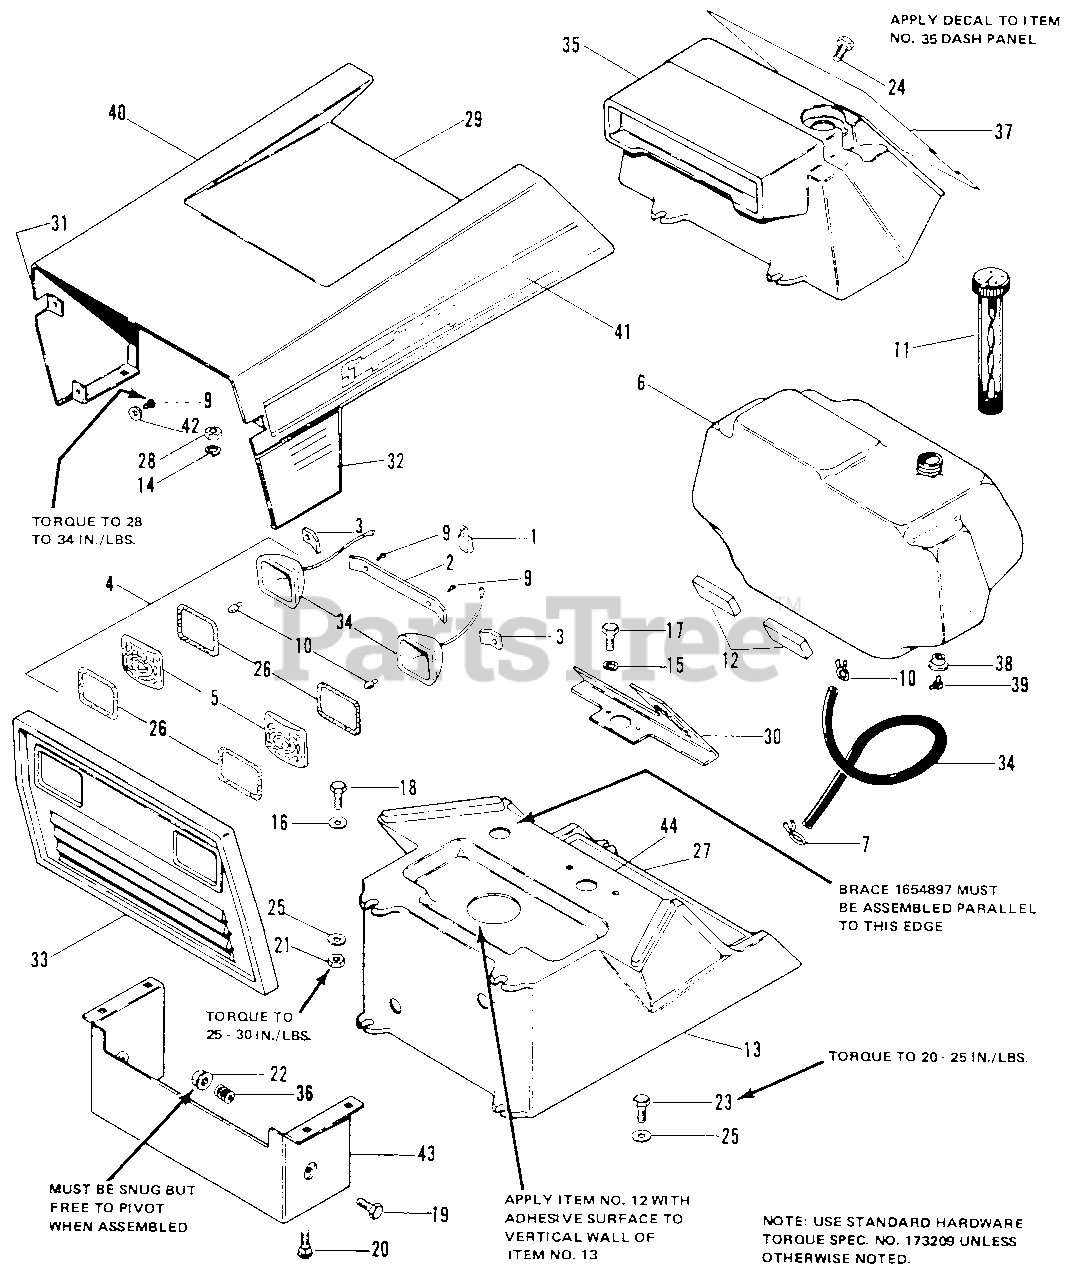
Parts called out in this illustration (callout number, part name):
1	CONNECTOR, Insulated
2	CLIP, Center Headlight
3	CLIP, Side Headlight
4	LlGHT ASSEMBLY
5	LENS, Clear Plastic
7	CLAMP, Hose
9	SCREW, Round Hd., Phillips,No. 10-32 x 3/8
10	BULB, No. 1156
11	CAP, Fuel Tank
12	PAD, Fuel Tank
13	DASHBOARD, Lower
14	LOCKWASHER, 1/4
15	LOCKWASHER, 3/8
16	WASHER, Plain, 1/4
17	CAPSCREW, Hex, 3/8-16 x 1
18	CAPSCREW, Hex, 1/4-20 x 1-1/4
19	CAPSCREW, Hex, 5/16-18 x 1-1/4
20	BOLT, Carriage, 1/4-20 x 5/8
21	LOCKNUT, Hex, Full, 1/4-20
22	LOCKNUT, Hex, Flange,5/16-18
23	SCREW, Hex, Washer, Taptite, 1/4-20 x 1
24	SCREW, Taptite, 1/4-20 x 3/4
25	LOCKWASHER, Dish Type, 1/4
26	GASKET, Lens
27	DECAL, Shift Pattern
28	NUT, Hex, Full, 1/4-20
29	HOOD ASSEMBLY
30	BRACE, Dashboard
31	DECAL, System 4208, L.H.
32	DECAL, System 4208, R.H.
34	REFLECTOR ASSEMBLY
35	DASHBOARD, Upper
37	DECAL, Dash
40	DECAL, Hood, R.H.
41	DECAL, Hood, L.H.
42	WASHER, Plain, No. 10
44	DECAL, Safety Warning
